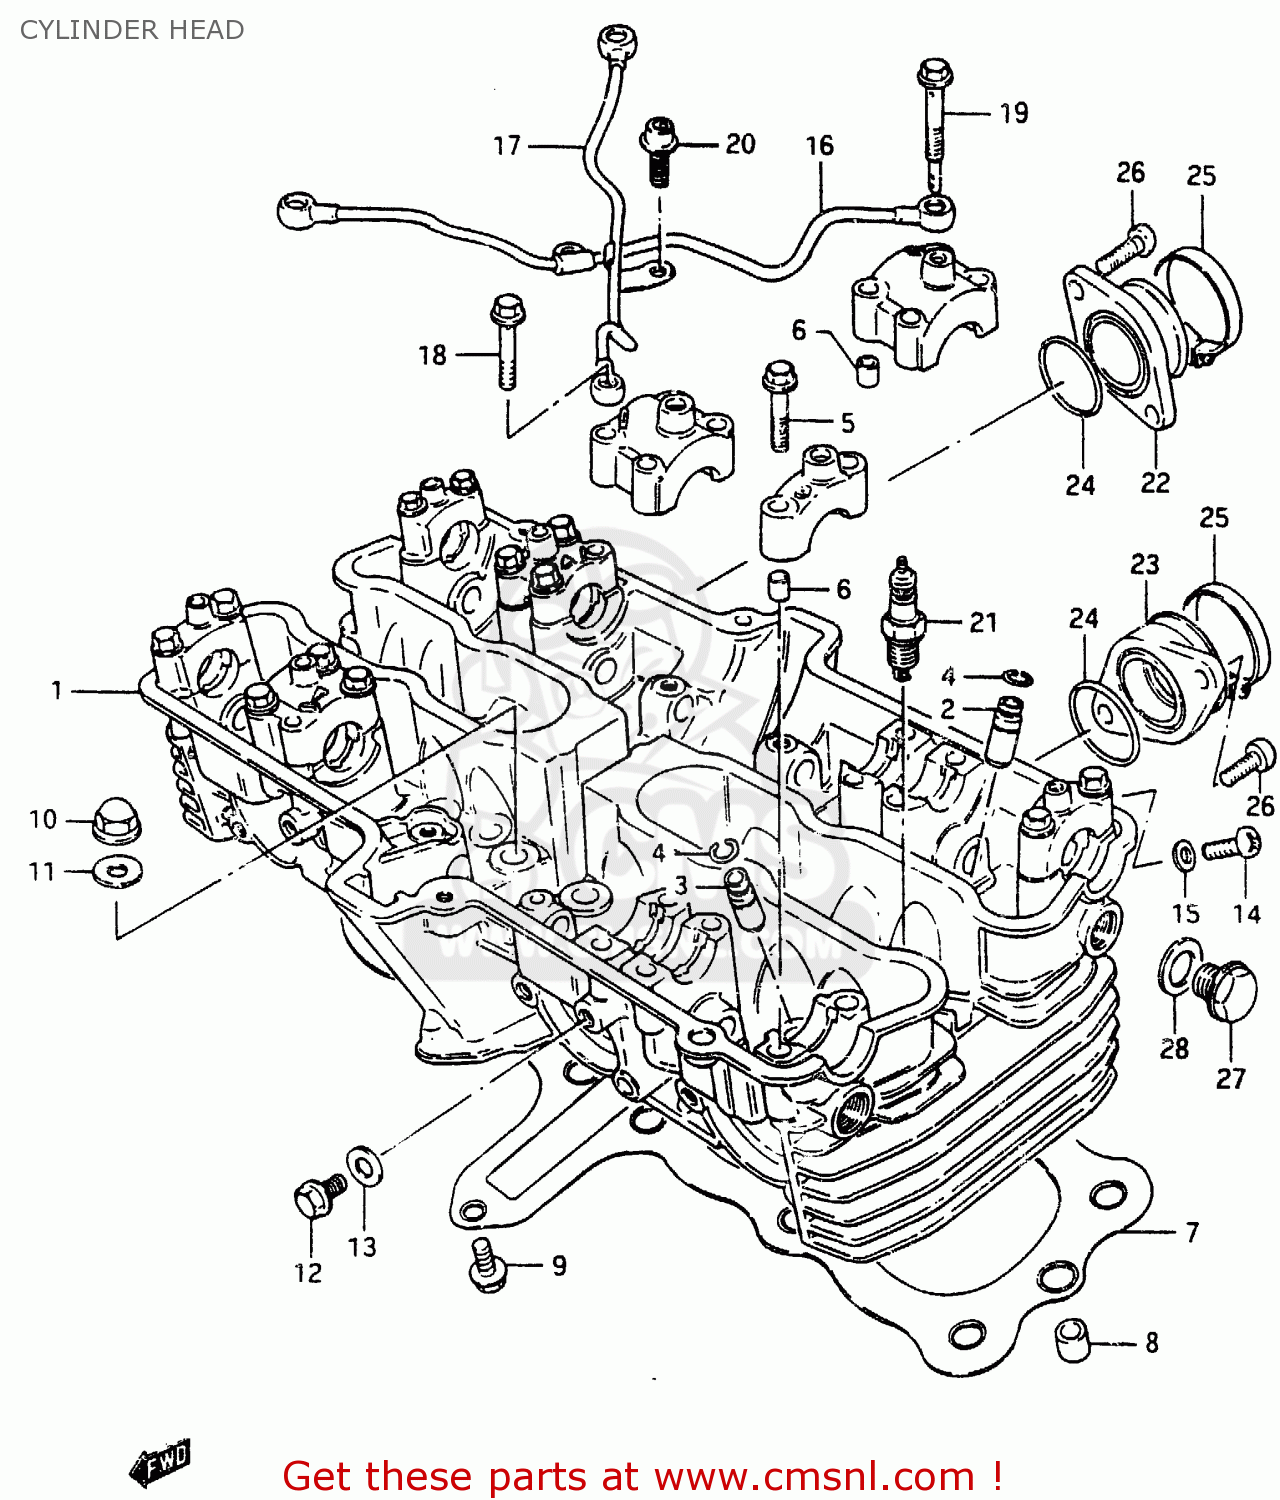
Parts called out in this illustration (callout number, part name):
1	HEAD,CYLINDER
2	GUIDE,INTAKE VALVE
3	GUIDE,INTAKE VALVE
4	RING,SNAP
5	BOLT(6X39)
6	PIN(6.2X8X11)
7	GASKET,CYLINDER HEAD (NAS)
8	PIN
9	BOLT
10	NUT
11	GASKET(10.5X22X2) (NAS)
12	BOLT
13	GASKET(6.2X13X1.2) (NAS)
14	SCREW
15	GASKET(5.3X9.3X1.2) (NAS)
16	PIPE,OIL CYLINDER HEAD NO.1
17	PIPE,OIL CYLINDER HEAD
18	UNION
19	BOLT,UNION
20	BOLT
21	SPARK PLUG D8EA
22	PIPE,INTAKE
23	PIPE,INTAKE
24	O RING(D:2.4,ID:37.7)
25	CLAMP
26	SCREW
27	PLUG
28	GASKET(14X19.2X2) (NAS)
